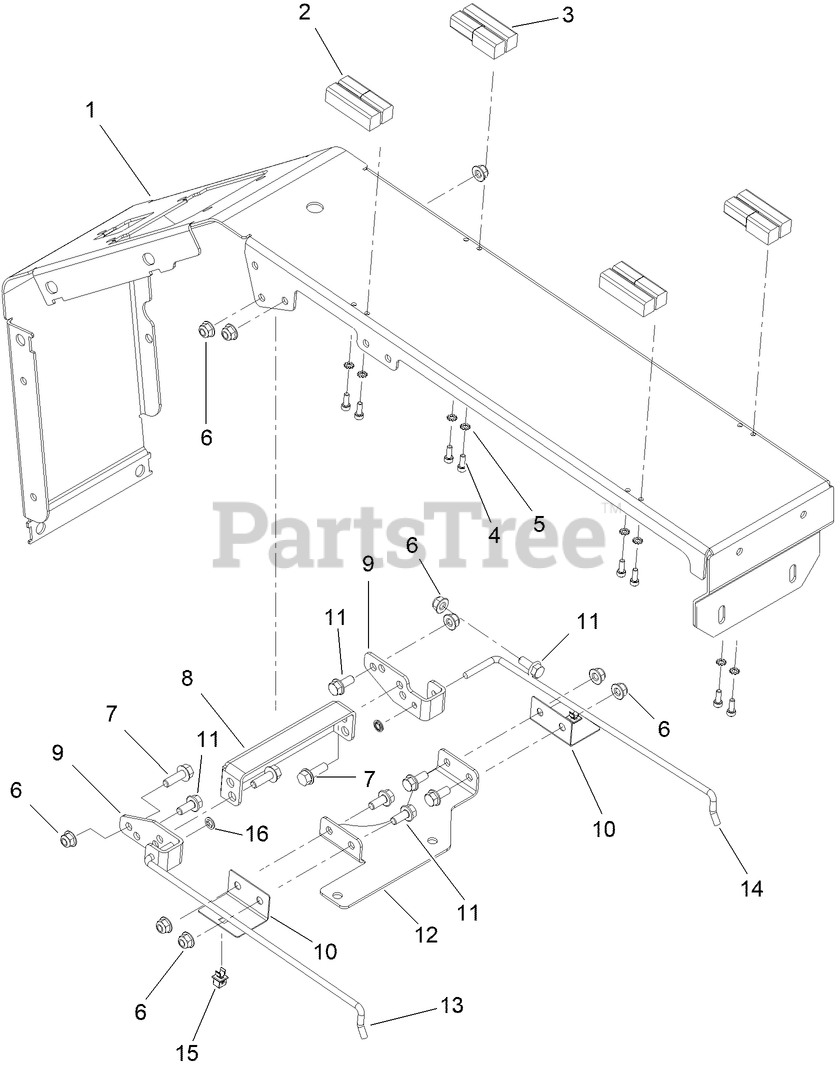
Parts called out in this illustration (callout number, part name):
1	SUPPORT
2	LIFT-OFF HINGE (OFFSET)
3	LIFT-OFF HINGE (OFFSET)
4	SCREW -HSH
5	WASHER-LOCK, EXT
6	NUT-HF, NI
7	SCREW-HHF
8	CROSS BRACE
9	SUPPORT, PROP ROD
10	TAB, PROP ROD
11	SCREW-HHF
12	BRACKET-AIR FILTER
13	PROP ROD, RIGHT
14	PROP ROD, LEFT
15	PROP ROD CLIP
16	PUSH NUT (1/4)
